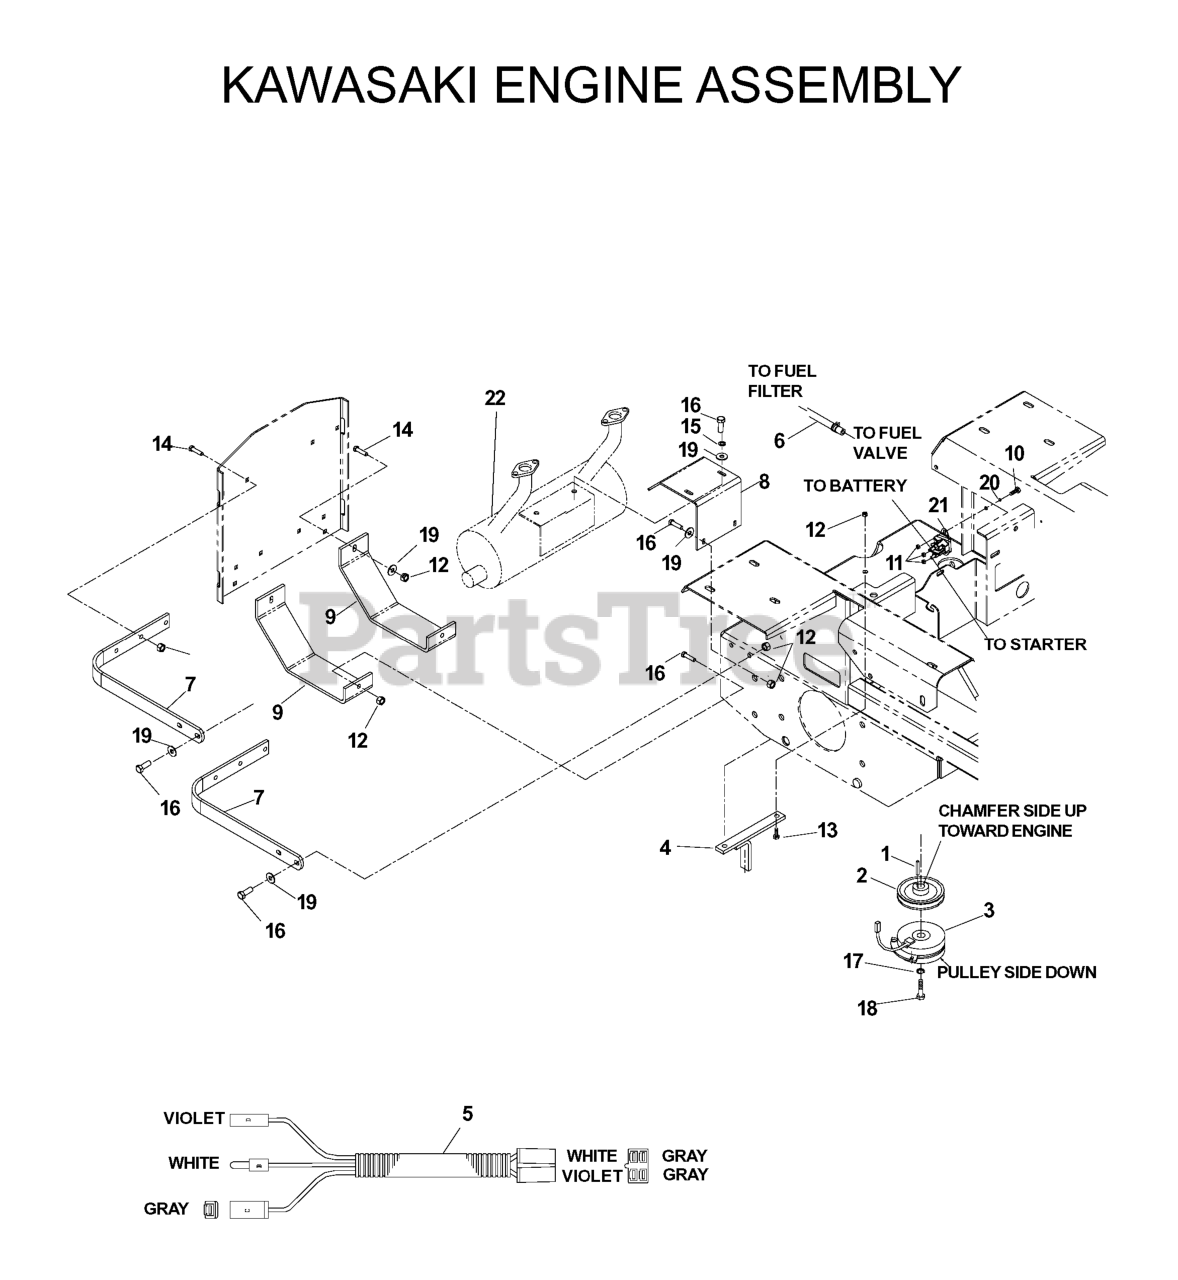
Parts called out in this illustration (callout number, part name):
1	KEY, 1/4 SQ X 1 1/4
3	CLUTCH-200 FT LB(RPLS 5218-102
4	CLUTCH TIE DOWN
5	KAW PIGTAIL
6	FUEL LINE 29.5"
7	ENGINE SHROUD BRKT
8	MUFFLER BRACKET
9	SKID PLATE
10	HCS 1/4C X 5/8
11	NUT.1/4-20.HEX.NYLOC.ZD
12	NUT 5/16 NYLOC
13	HCS 5/16C X 1 3/4
14	RHSSNB 5/16C X 1.0
15	WASHER.LOCK.HVY.HLCL.SPR.5/16
16	HCS 5/16C X 1
17	WASHER 7/16 LOCK
18	BOLT 7/16F X 2 1/2
19	WASHER 5/16 FLAT
20	WASHER 1/4 INT TOOTH
22	MUFFLER 18HP KAW
539105897	MUFFLER KAWASAKI GEN II
